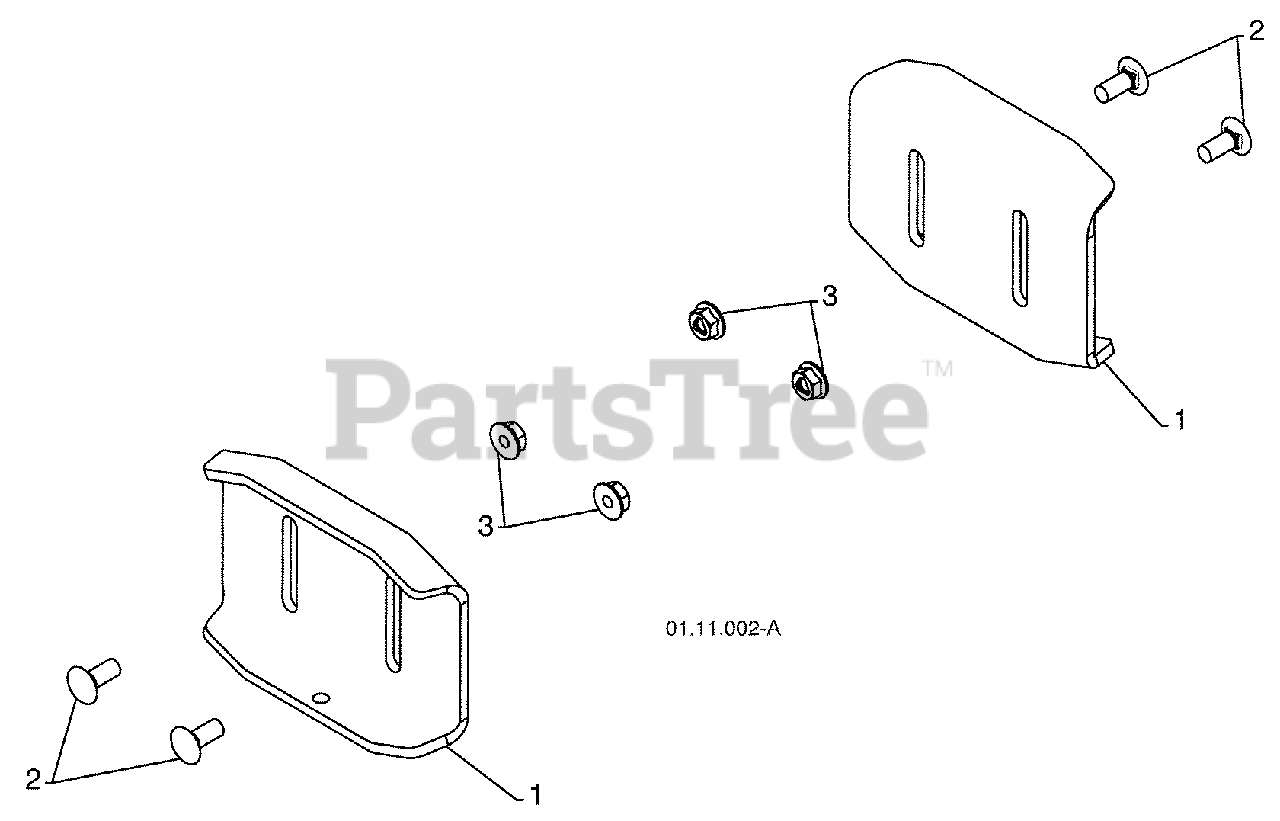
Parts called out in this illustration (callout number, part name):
1	SKID PLATE
2	CARRIAGE BOLT 5/16-18 X .750
3	NUT 5/16-18
